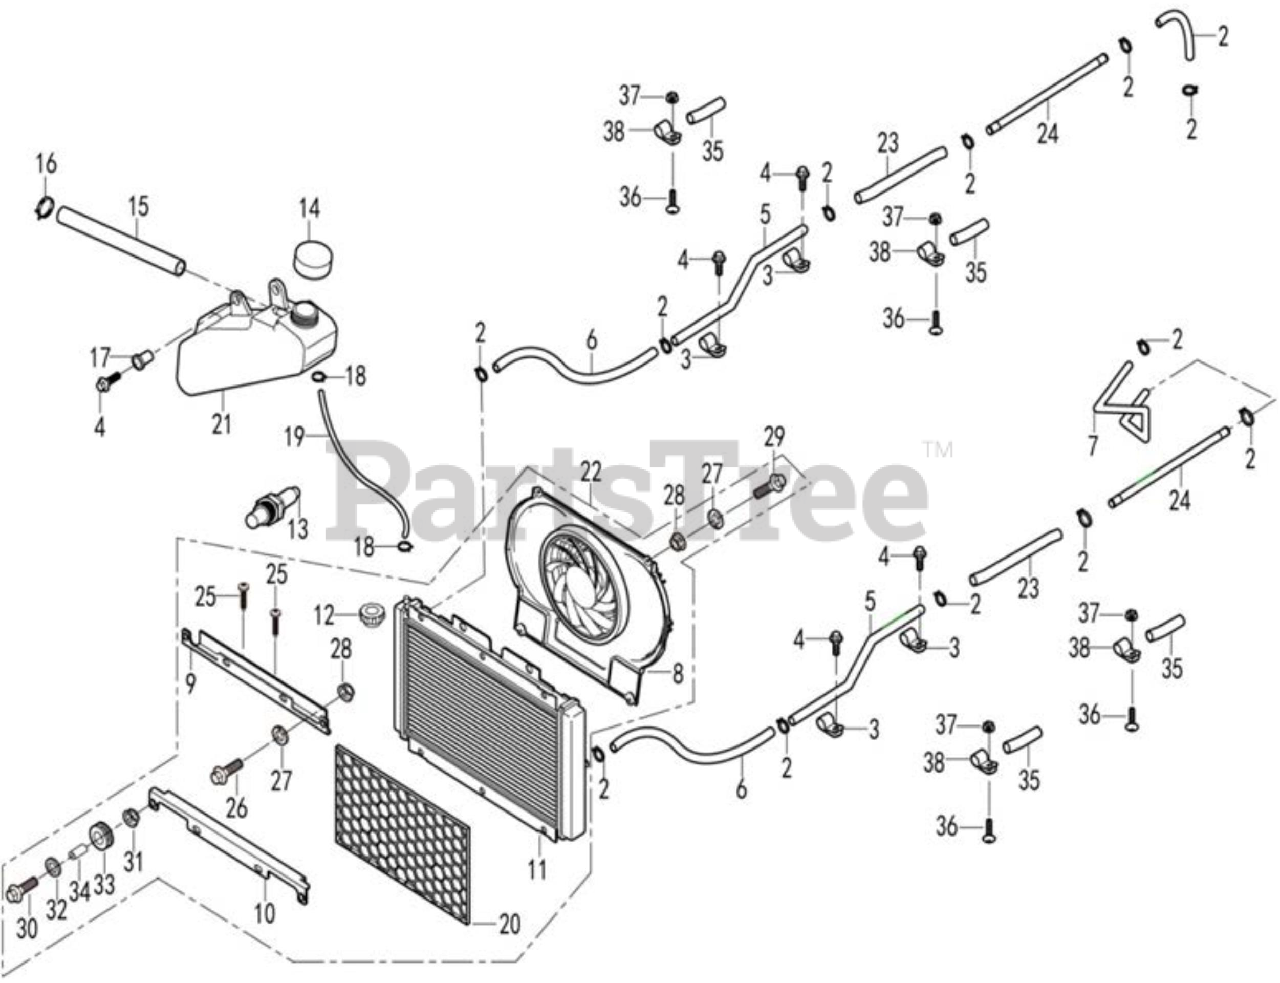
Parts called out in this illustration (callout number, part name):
1	water inlet
2	Screw Clip D
3	Clip V, Water Pipe
4	Hexagon Flange Bolt M6X16
5	Metal Water Pipe I
6	water inlet
7	Exhalent siphon
8	Cooler Fan Assy
9	Radiator Support I
10	Radiator Support 2
11	Weding Water Tank Assy
12	Water Tank Cover
13	Water Temperature Sensor
14	Secondary water tank cover
15	Exhalent siphon for auxiliary kettle
16	Flexible Clamp D
17	Bush 6.5X22X6.5
18	Elastic hoop C
19	water inlet for auxiliary kettle
20	Radiator Cover
21	Second Water Tank
22	Cooling water tank component
23	water inlet
24	Metal Water Pipe I
25	Self-tapping screw ST4.8X13
26	Flange Bolt M6X14
27	Spring Washer 6
28	Flange Nut M6
29	Hexagon Bolt M6X18
30	Flange Bolt M6X25
31	Flange Nut M6
32	Flat washer 6
33	Water tank bracket Ring
34	Water tank bracket Bushing
35	Water pipe boot
36	Cross pan screw M6X16
38	Water pipe clamp
